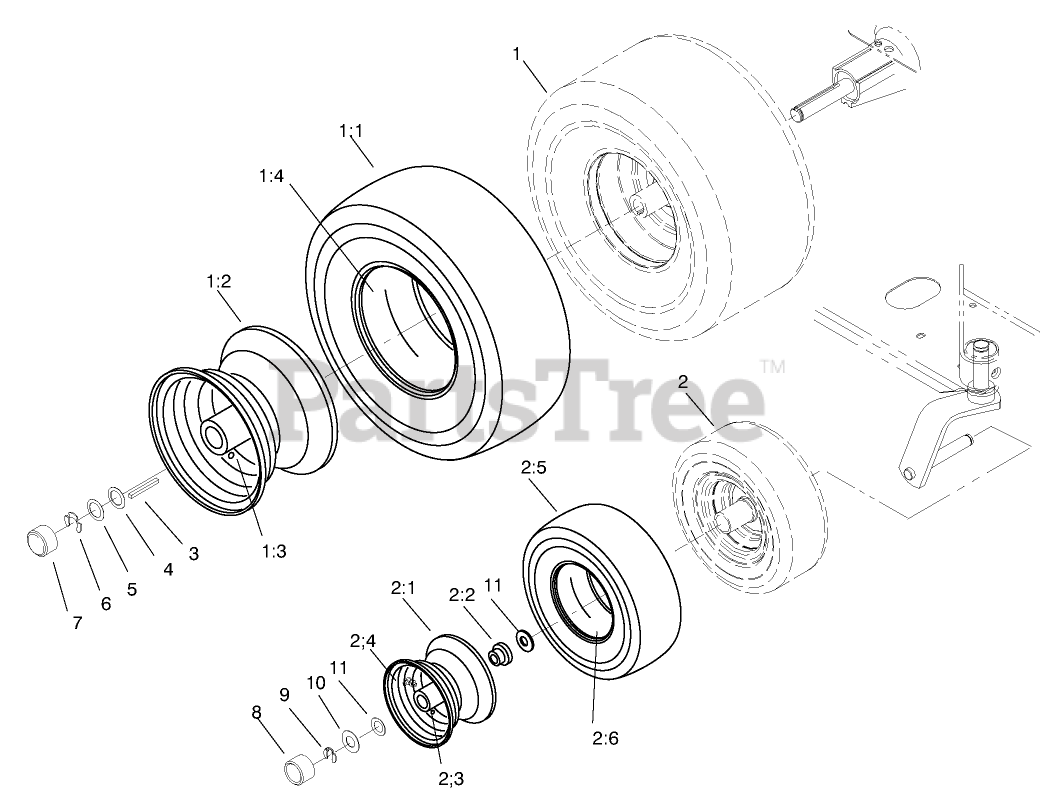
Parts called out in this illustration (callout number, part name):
1	Wheel/Tire Asm Rear
1:1	TIRE-18X9.50-8 TT RS
1:2	ASSEMBLY - REAR WHEEL
1:3	VALVE
1:4	TUBE-TIRE
2	Wheel/Tire Asm Front
2:1	Wheel
2:2	BEARING-WHEEL
2:3	VALVE
2:4	ZERK-GREASE
2:5	TIRE 11 X 400-5 RIB
2:6	TUBE-TIRE 11X4.00-5
3	KEY-SQUARE
4	Washer
5	WASHER
6	RING-RETAINING
7	HUBCAP
8	HUB CAP-FLAT BLACK
9	KLIP-RING .75"
10	WASHER-WHEEL
11	WASHER-SHIM
